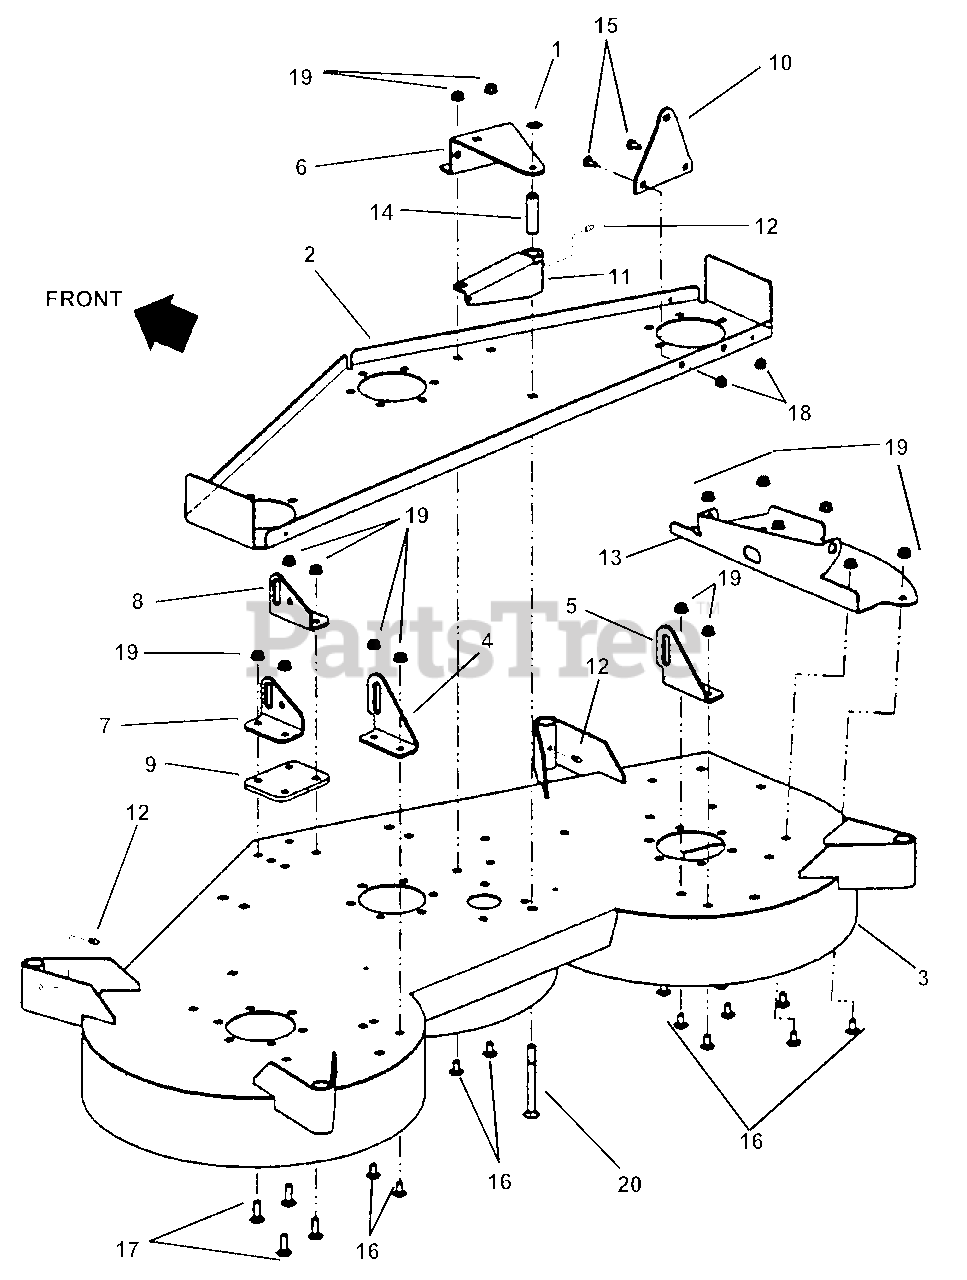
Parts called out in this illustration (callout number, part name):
1	RETAINER, 3/8" Bolt
2	STIFFENER, Deck
3	WELDMENT, 48" Deck
4	HANGER, R.H. Rear
5	HANGER, L.H. Rear
6	BRACKET, Pulley Mounting
7	BRACKET, L.H. Front Lift
8	BRACKET, R.H. Front Lift
9	SPACER, 48" Deck Hanger
10	PLATE, 48" Anchor (weldment)
11	ASSEMBLY, Idler Arm/Lube Fitting
12	LUBE FITTING, Straight (press-fit for .187 dia. Hole)
13	BRACKET, Hinge (48" Deck)
14	SPACER, Pivot Collar
15	BOLT, 1/4-20 x 5/8" Short Neck Carriage
16	BOLT, 5/16-18 x 5/8" Short Neck Carriage, Grade 5
17	BOLT, 5/16-18 x 1" Short Neck Carriage, Grade 5
18	NUT, 1/4"-20 Hex Flange Lock, Grade 5
19	NUT, 5/16-18 Hex Flange Lock, Grade 5
20	BOLT, 3/8-16 x 4" Square Neck Carriage, Grade 5
